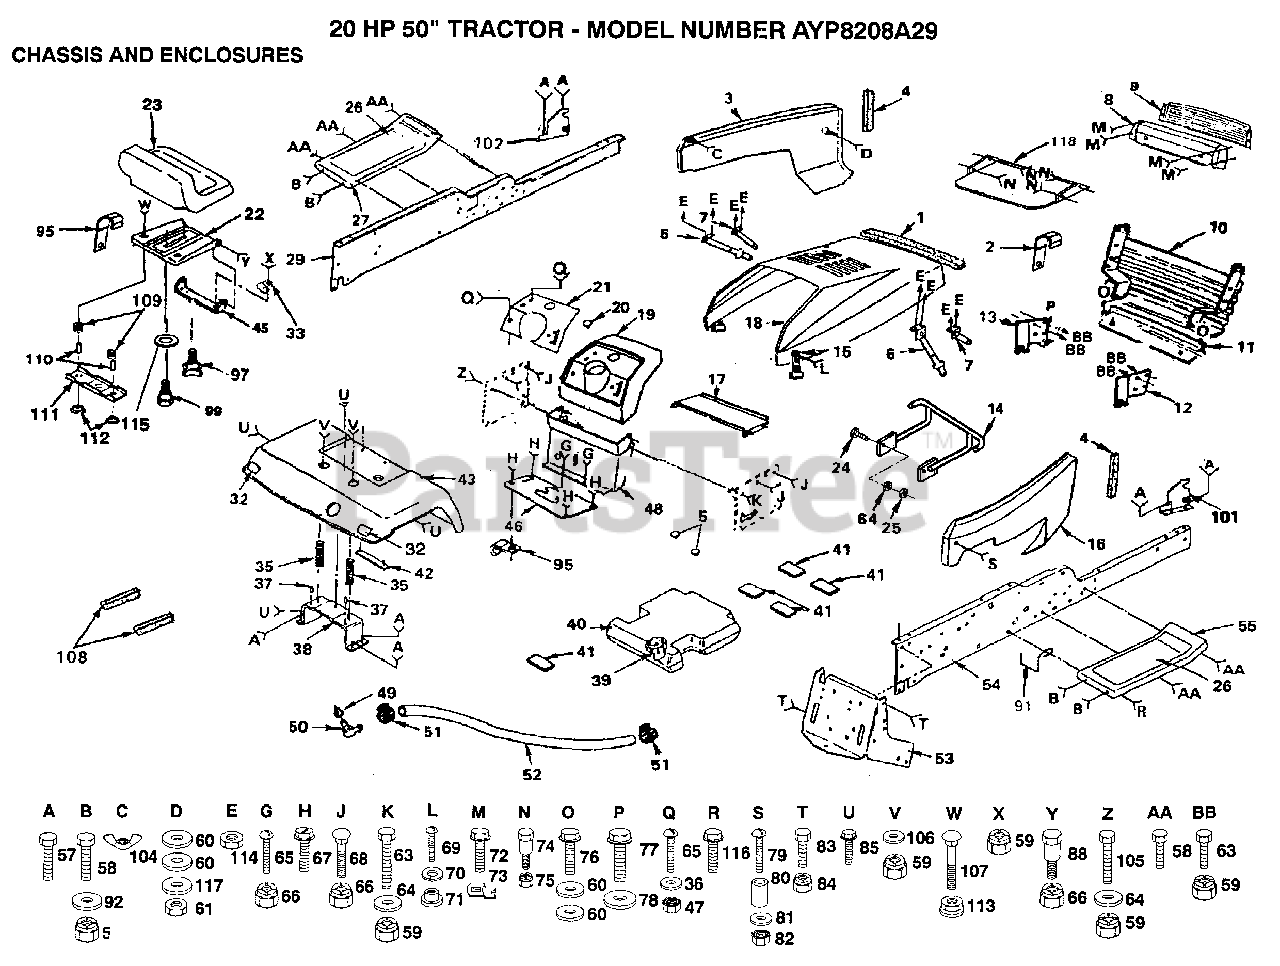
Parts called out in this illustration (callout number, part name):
1	FOAM STRIP T
3	"PANEL,SIDE LH "
4	FOAM STRIP T
5	CAP SPRING
9	LENS LT
12	SUPPORT RH YTH
13	SUPPORT LH YTH
14	BUMPER ASSY.
15	HOOD LATCH T
16	"PANEL,SIDE RH "
20	PLUG-DASH T
24	BOLT
26	FOOTREST PAD
32	REFLECTOR-TAIL YT
33	CLIP T
35	SPRING COMPRESSIO
36	WASHER
37	NUT-PUSH YT
41	PAD-SPACER LT
43	FENDER
46	COVER GATE SHIFT
48	DASH ASSEMBLY
49	BUSHING OUTLET T
50	FUEL TANK STEM GT
51	HOSE CLAMP
57	SCREW
60	WASHER PM
63	BOLT
64	WASHER
65	SCREW
67	SCREW
68	BOLT
69	SCREW
70	LOCKWASHER
71	WELDNUT
73	"""J"" FASTENER LT"
76	SCREW
77	SCREW
78	WASHER
79	SCREW
80	SPACER LT
81	WASHER
83	BOLT
84	NUT GTV
85	SCREW LT
91	BELT RETAINER GT
92	WASHER
97	"KNOB 1/2"" YT"
99	"BOLT,SHOULDER"
101	SUPPORT RH YTH
102	SUPPORT LH YTH
106	WASHER
108	STRIP FORM
109	SPRING COMPRESSED
110	SPACER SPLIT
111	BRKT SWITCH
112	BUSHING
114	NUT
115	WASHER
116	SCREW GTV
117	WASHER
118	"SHIELD,HEAT"
